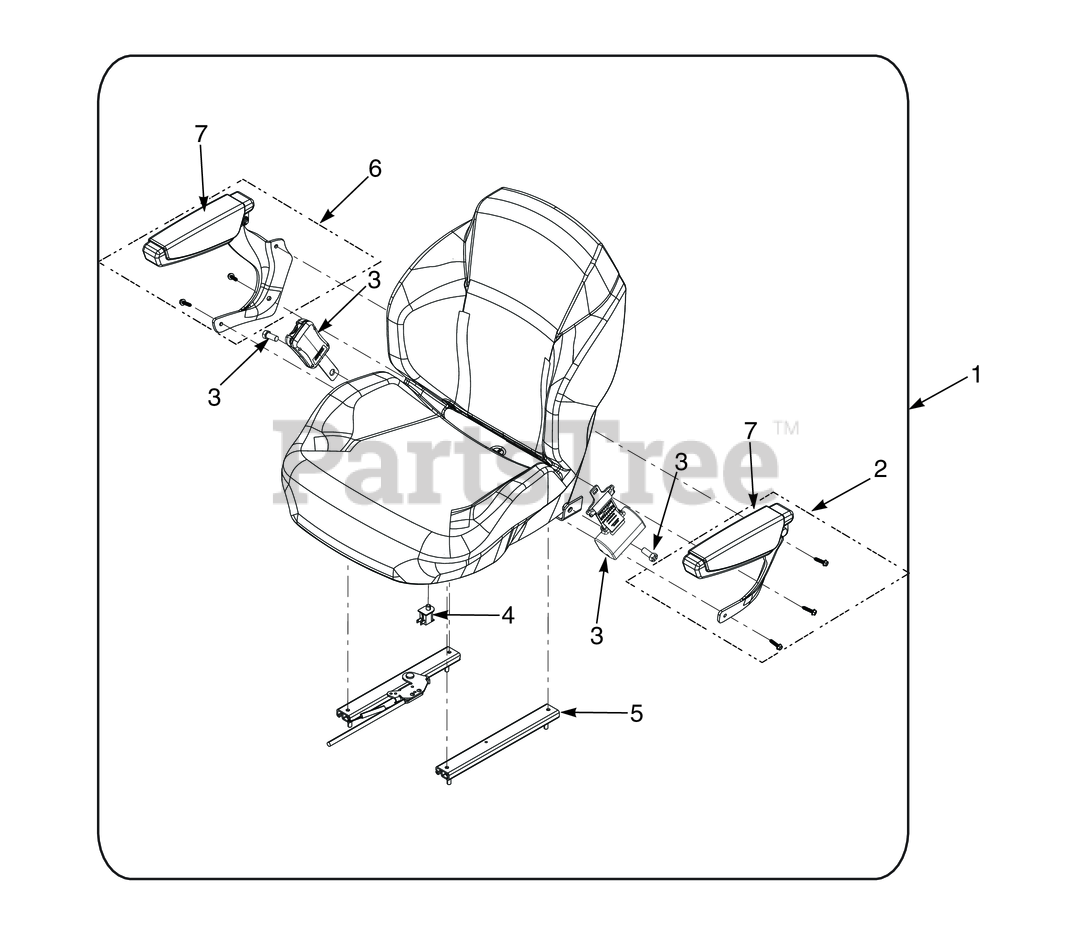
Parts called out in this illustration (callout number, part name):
1	Seat Assembly (INCL 14)
2	Armrest Kit, LH
3	Seat Belt Kit, Retractable - SCZII
4	Switch, Interlock, Normally Open
5	Track Kit
6	Armrest Kit, RH
7	Pad, Armrest
